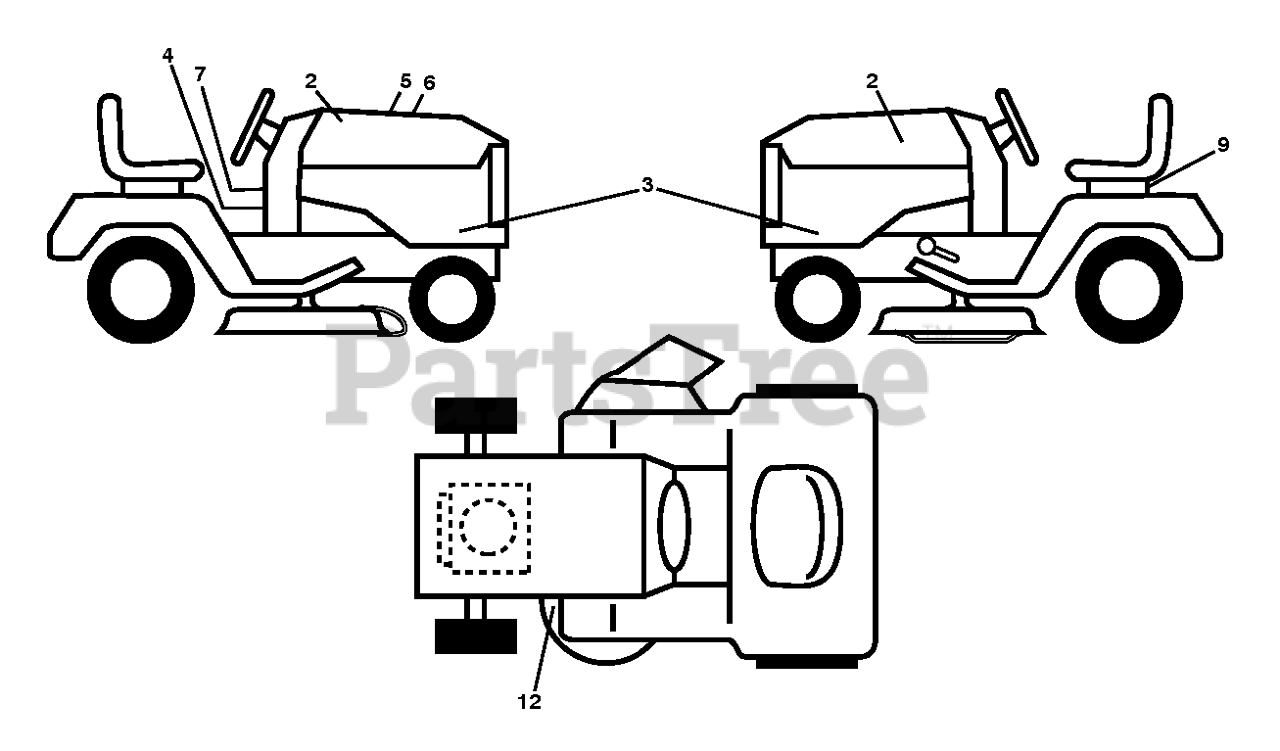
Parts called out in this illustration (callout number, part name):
2	DECAL.BADGE.170MM.TEXTLOGO.
3	RP DECAL.PNL.SD.YTH21K46.HUSQ
4	DECAL, WARNING SPARK ARRESTOR
5	DECAL.WARNING.CUST.RESP.E85.
7	LABEL.EMISS.CA.HUSQ/LOWES.2011
9	DECAL.FENDER.WARNING
12	DECAL V BELT SCHEMATIC
